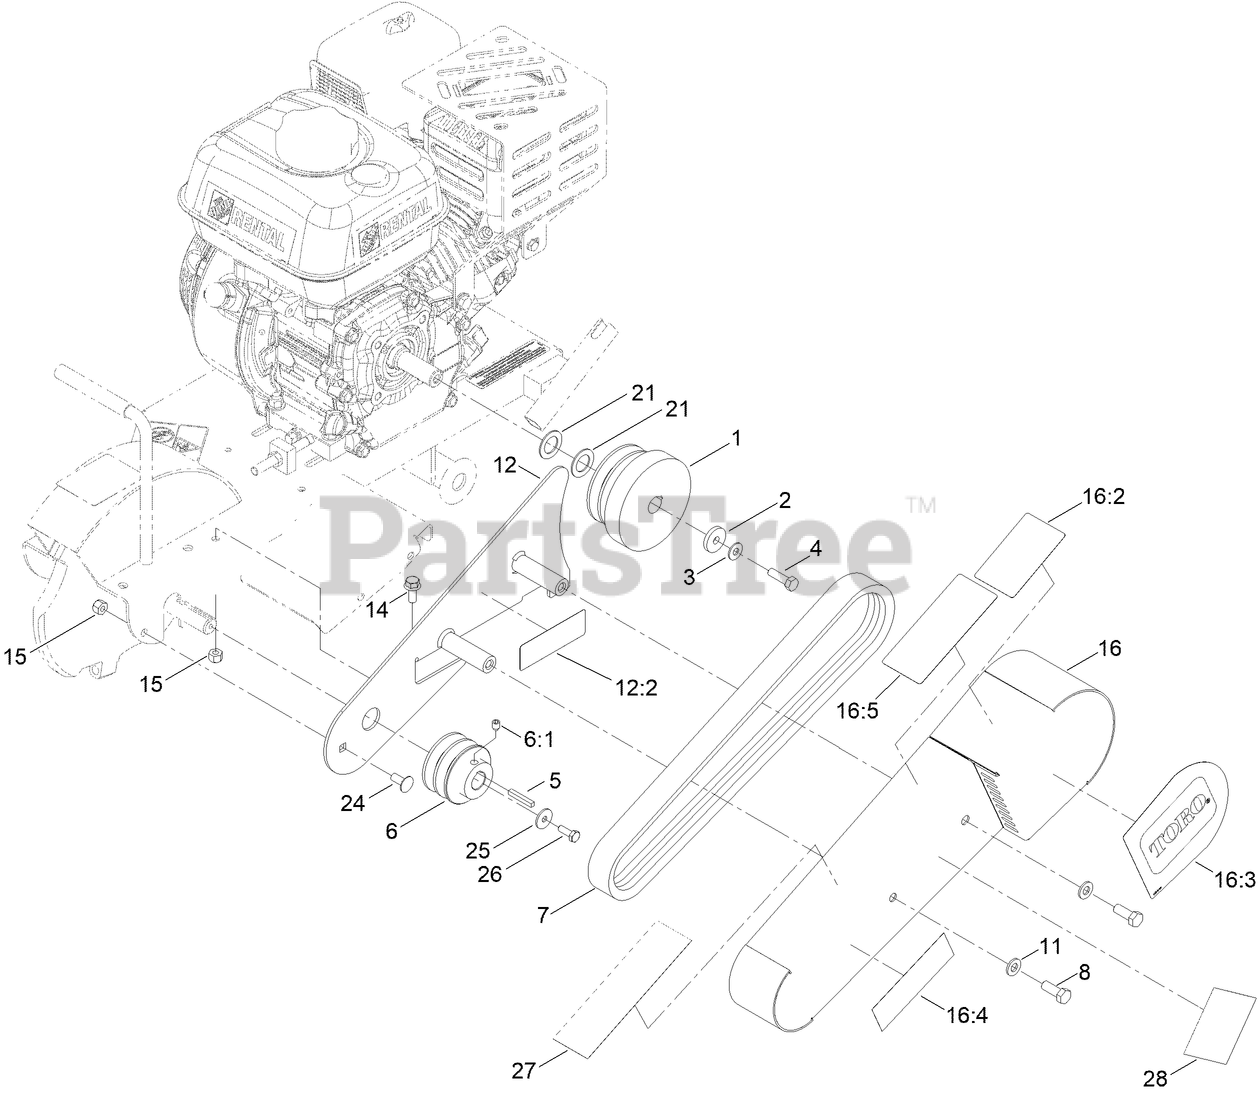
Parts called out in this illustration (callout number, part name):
1	CLUTCH-CENTRIFUGAL
2	WASHER-HARDENED
3	WASHER-FLAT
4	SCREW-HH
5	KEY-SQUARE
6	PULLEY-FRONT
6:1	SCREW-HSH
7	BELT-V, BANDED
8	SCREW-HH
11	WASHER-FLAT
12	PLATE-GUARD, INNER
12:2	DECAL-WARNING
14	SCREW-HHF
15	NUT-LOCK, NI
16	BELT GUARD ASM
16:2	DECAL-CAUTION
16:5	DECAL-SERVICE
21	WASHER-THRUST
24	SCREW-CARR
25	WASHER
26	SCREW-HH
27	DECAL-CPER0014
28	DECAL-CPER0052
